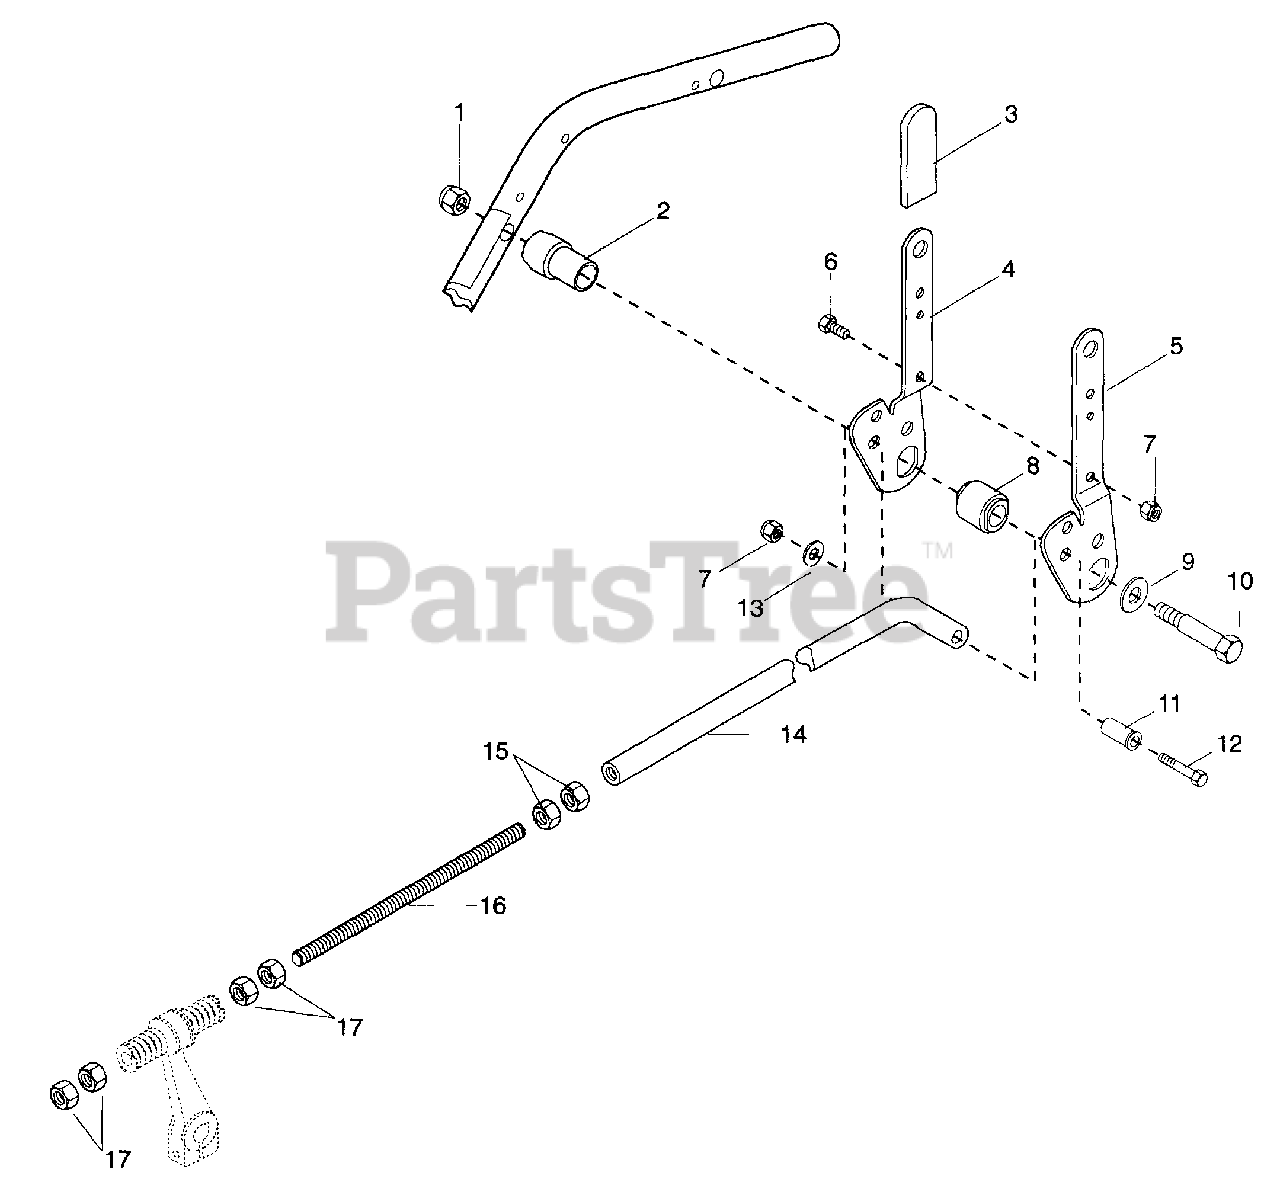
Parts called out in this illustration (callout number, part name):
1	Nut-Locking-Nylon .375-16
2	Pivot, Hand Lever Left Hand
3	Grip, Handle
4	Handle, Control Right Hand
5	Handle, Control Left Hand
6	Bolt-Hex .25-20 x .63
7	Nut-Locking-Nylon .250-20
8	Bushing, Flange .751 x 1.13 x 1.07
9	Washer-Flat-Steel .531 x 1.062 x .095
10	Bolt-Hex .38-16 x 3.5
11	Bushing-Flange .257 x .38 x 1.080
12	Bolt-Hex .25-20 x 1.50 Grade 5
13	Washer-Flat-Steel .281 x .62 x .065
14	Rod, Control Hi-Lo
15	Nut-Hex .375-16
16	Rod, Extension
17	Nut-Jam .375-16
